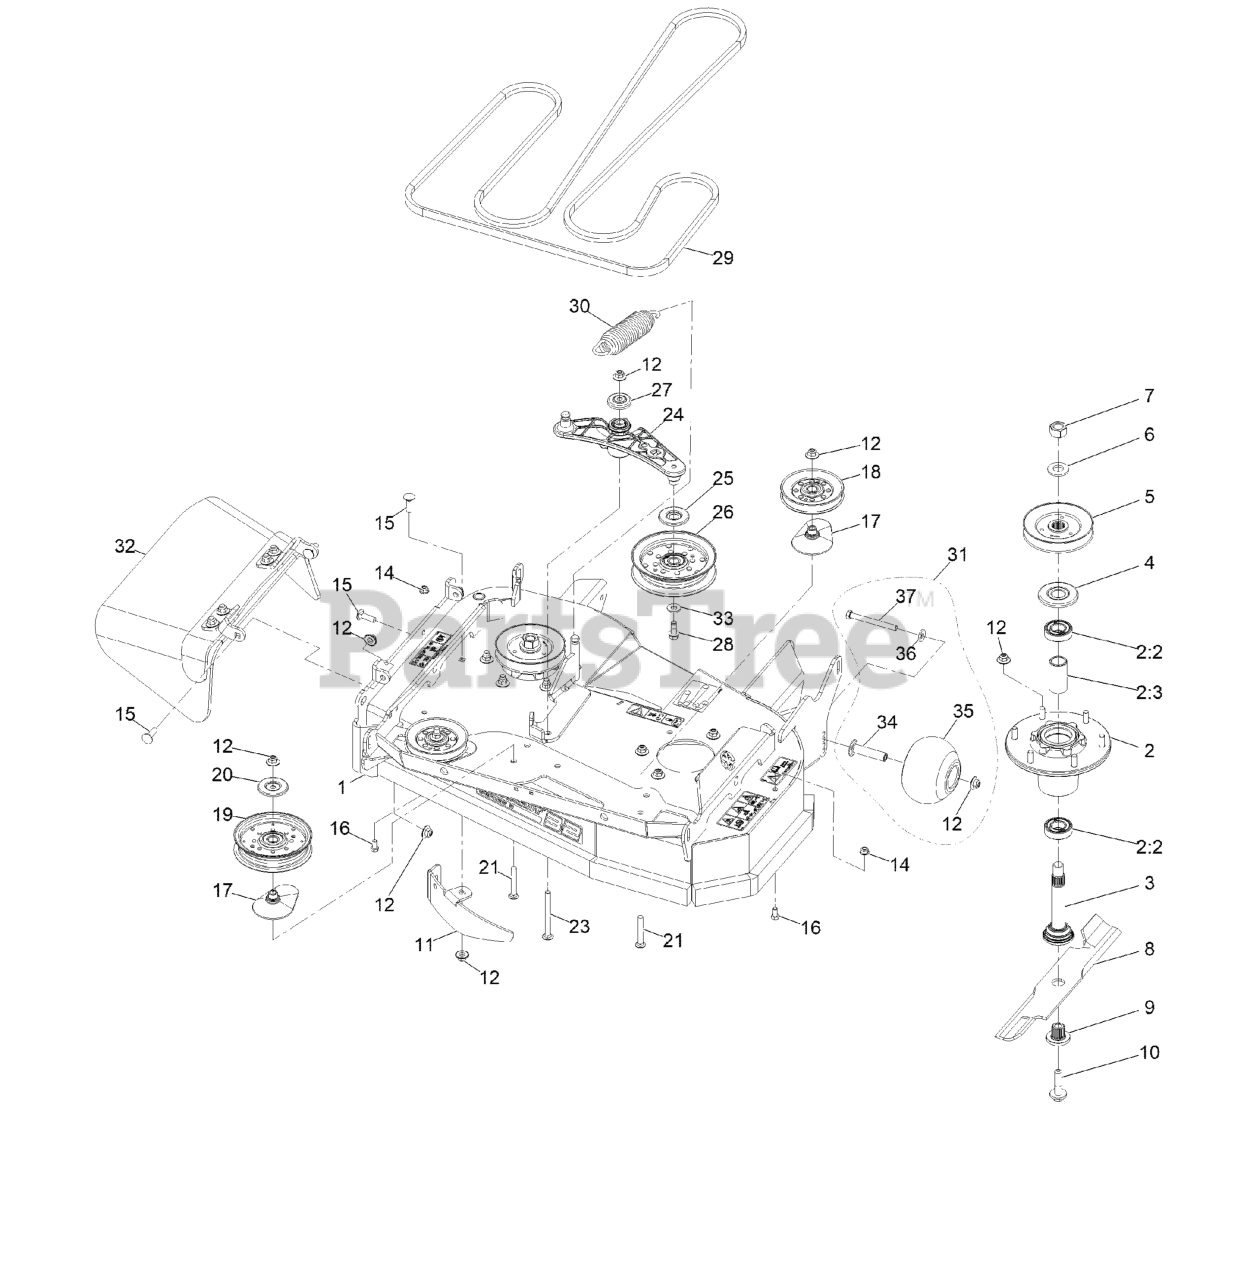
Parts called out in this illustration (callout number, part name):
1	ASM-DECK DECALS 32
2	ASM-CUTTER HSG WITH BEARINGS
2:2	BEARING-BALL
2:3	SPACER-BEARING
3	ASM-SPINDLE AND SEAL
4	GUARD,BEARING TOP .989
5	SHEAVE-BLADE DRIVE
7	NUT-HEX
9	BUSHING,SPLINED
10	SCREW,SEMS 1/2-20 X 2.19
11	BAFFLE, DOGLEG
12	Nut-Nyloc 3/8-16 Flg
14	NUT-HF, NI
15	BOLT-CARR
16	SCREW-HH
17	SPACER-PULLEY
18	Idler - V 4.13 Eod-A
19	PULLEY-IDLER, FLAT
20	SHIELD-DUST
21	SCREW-CARR
23	SCREW-CARR
24	ASM.-ARM, IDLER
25	SHIELD-GUARD, DUST
26	IDLER-PULLEY, FLAT
27	GUARD-TOP
28	SCREW-HFH
30	SPRING-EXTENSION
31	KIT, ANTI-SCALP ROLLER
32	RUBBER DEFLECTOR ASM
33	WASHER-FLAT
34	AXLE, ROLLER
35	ROLLER-SCALP, ANTI
36	WASHER-BELLEVILLE
37	SCREW-HH 3/8-16 X 3 3/4 GR 8
